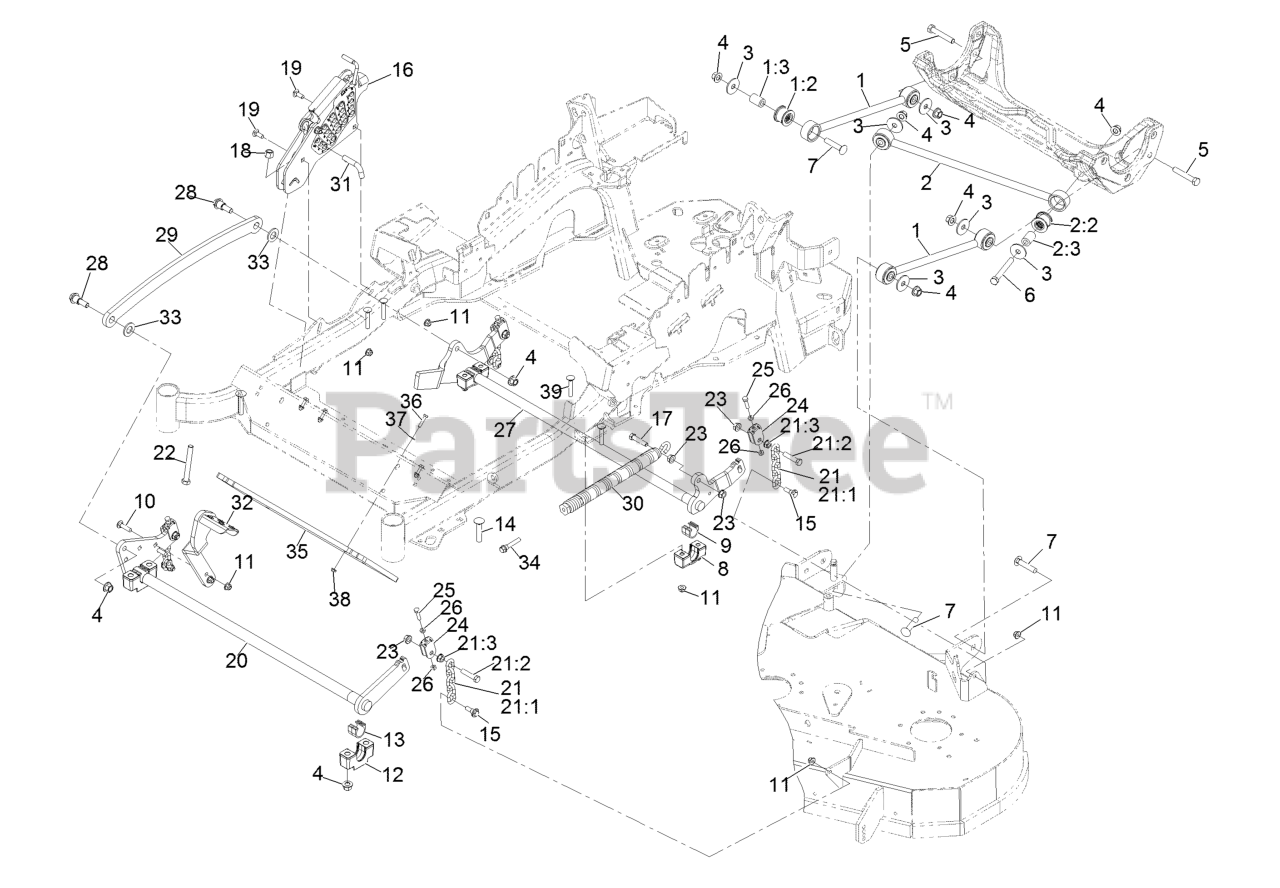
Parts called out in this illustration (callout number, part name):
1	Deck Strut ASM
1:2	Bushing-Suspension, Rubber
2	Panhard Rod ASM
2:2	Bushing-Suspension, Rubber
4	Nut-Lock 1/2-13
5	Screw-HH 1/2-13 X 3
6	Screw-HH 1/2-13 X 4
7	Bolt-Carriage 1/2-13 X 2 1/2
8	Support-Cross Shaft, Bearing Rear
9	Bearing-Cross Shaft, Rear
10	Bolt-Carriage 3/8-16 X 1 1/2
11	Nut-Nyloc 3/8-16 Flg
12	Support-Cross Shaft, Bearing
13	Bearing-Cross Shaft, Front
14	Bolt-Carriage 1/2-13 X 2 1/2 Spl Neck
15	Screw-Hex Flange 3/8-16 X 80
16	HOC ASM
17	Screw-HH 7/16-14 X 2
18	Nut-Nyloc 1/2-13
19	Bolt-Carriage 3/8-16 X 1
20	Decklift-Front
21	Deck Lift Chain ASM
21:1	Chain-Lift, Deck
21:2	Screw-HH 7/16-14 X 2
21:3	Nut-Whizlock 7/16-14
22	Bolt-HH 1/2-13 X 4 Tap
23	Nut-Whizlock 7/16-14
24	Yoke-Adjust, Deck
25	Screw-HH 5/16-18 X 1 1/4
26	Nut-Jam 5/16-18
27	Lift-Deck, Rear
28	Screw-Shoulder HHF 1/2-13 X 1.12
29	Link-Lift, Deck
30	Spring-Extension
31	Pin-HOC
32	Lever-Foot
33	Washer-3/4 SAE
34	Screw-Shcs 3/8-16 X 2.212
35	Weight-Toe Board
36	Screw-HH 1/4-20 X 1 1/4
37	Washer-1/4 SAE
38	Nut-Nyloc 1/4-20 Flg
39	Bolt-Carriage 3/8-16 X 2 1/4
